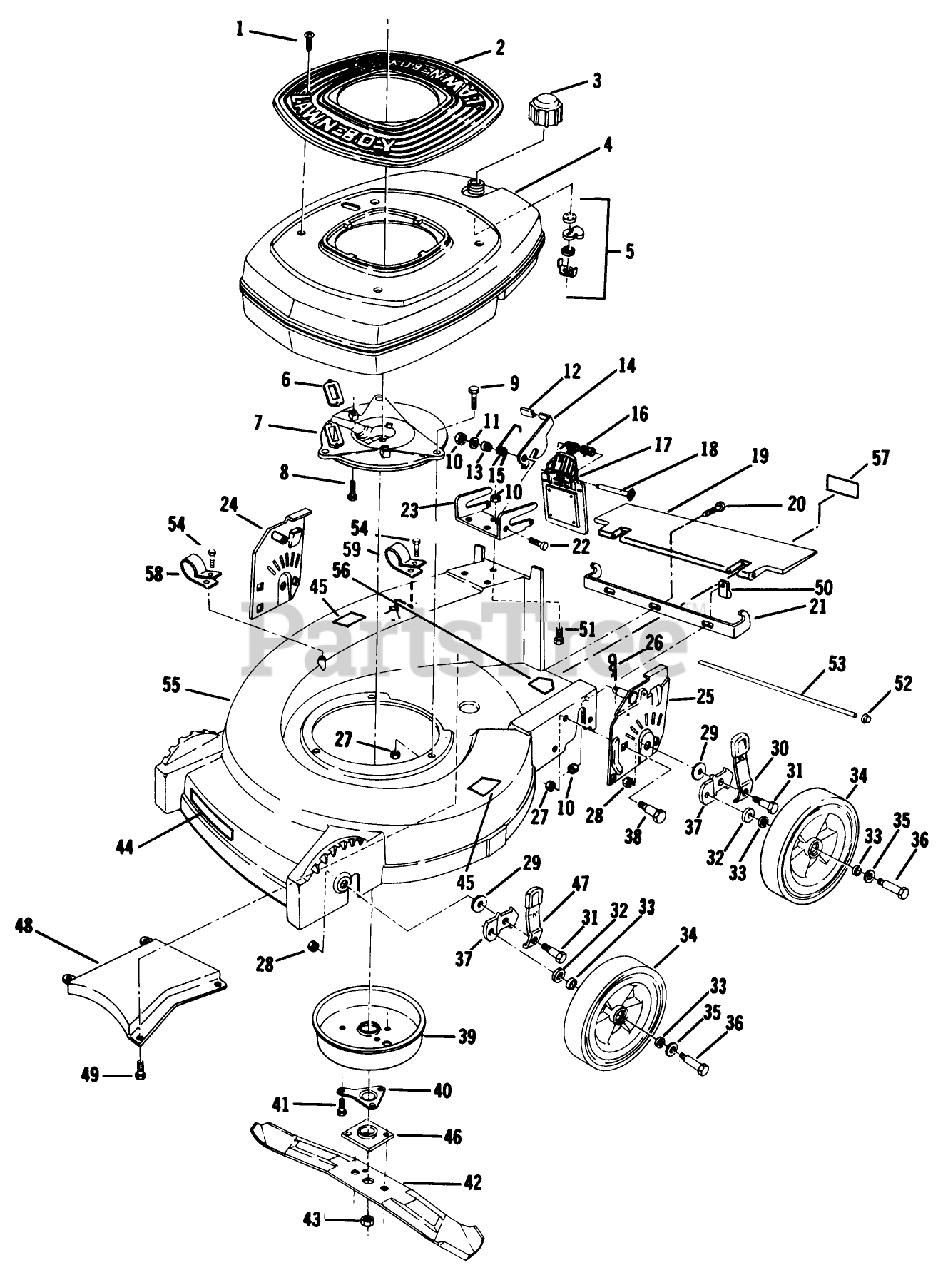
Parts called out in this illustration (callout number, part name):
1	SCREW - SELF TAPPING
3	FUEL CAP & INSERT
5	SHUT-OFF VALVE S
8	SCREW V
9	SCREW-HH
10	LOCKNUT E
15	SPRING
16	SPRING ASOC
18	ROD (RB&W)
19	T/SHIELD SM&P
26	HAIR PIN
27	NUT-LOCK F
28	LOCKNUT
29	WASHER
31	BOLT
32	WASHER WROUGHT
33	WASHER
35	SPACER
36	BOLT WHEEL
39	MUFFLER COVER F
40	SUPPORT F
41	SCREW
43	NUT-BLADE
46	PLATE AND COLLAR ASM
48	BAFFLE CHUTE PL
54	SCREW LAWRENCE
